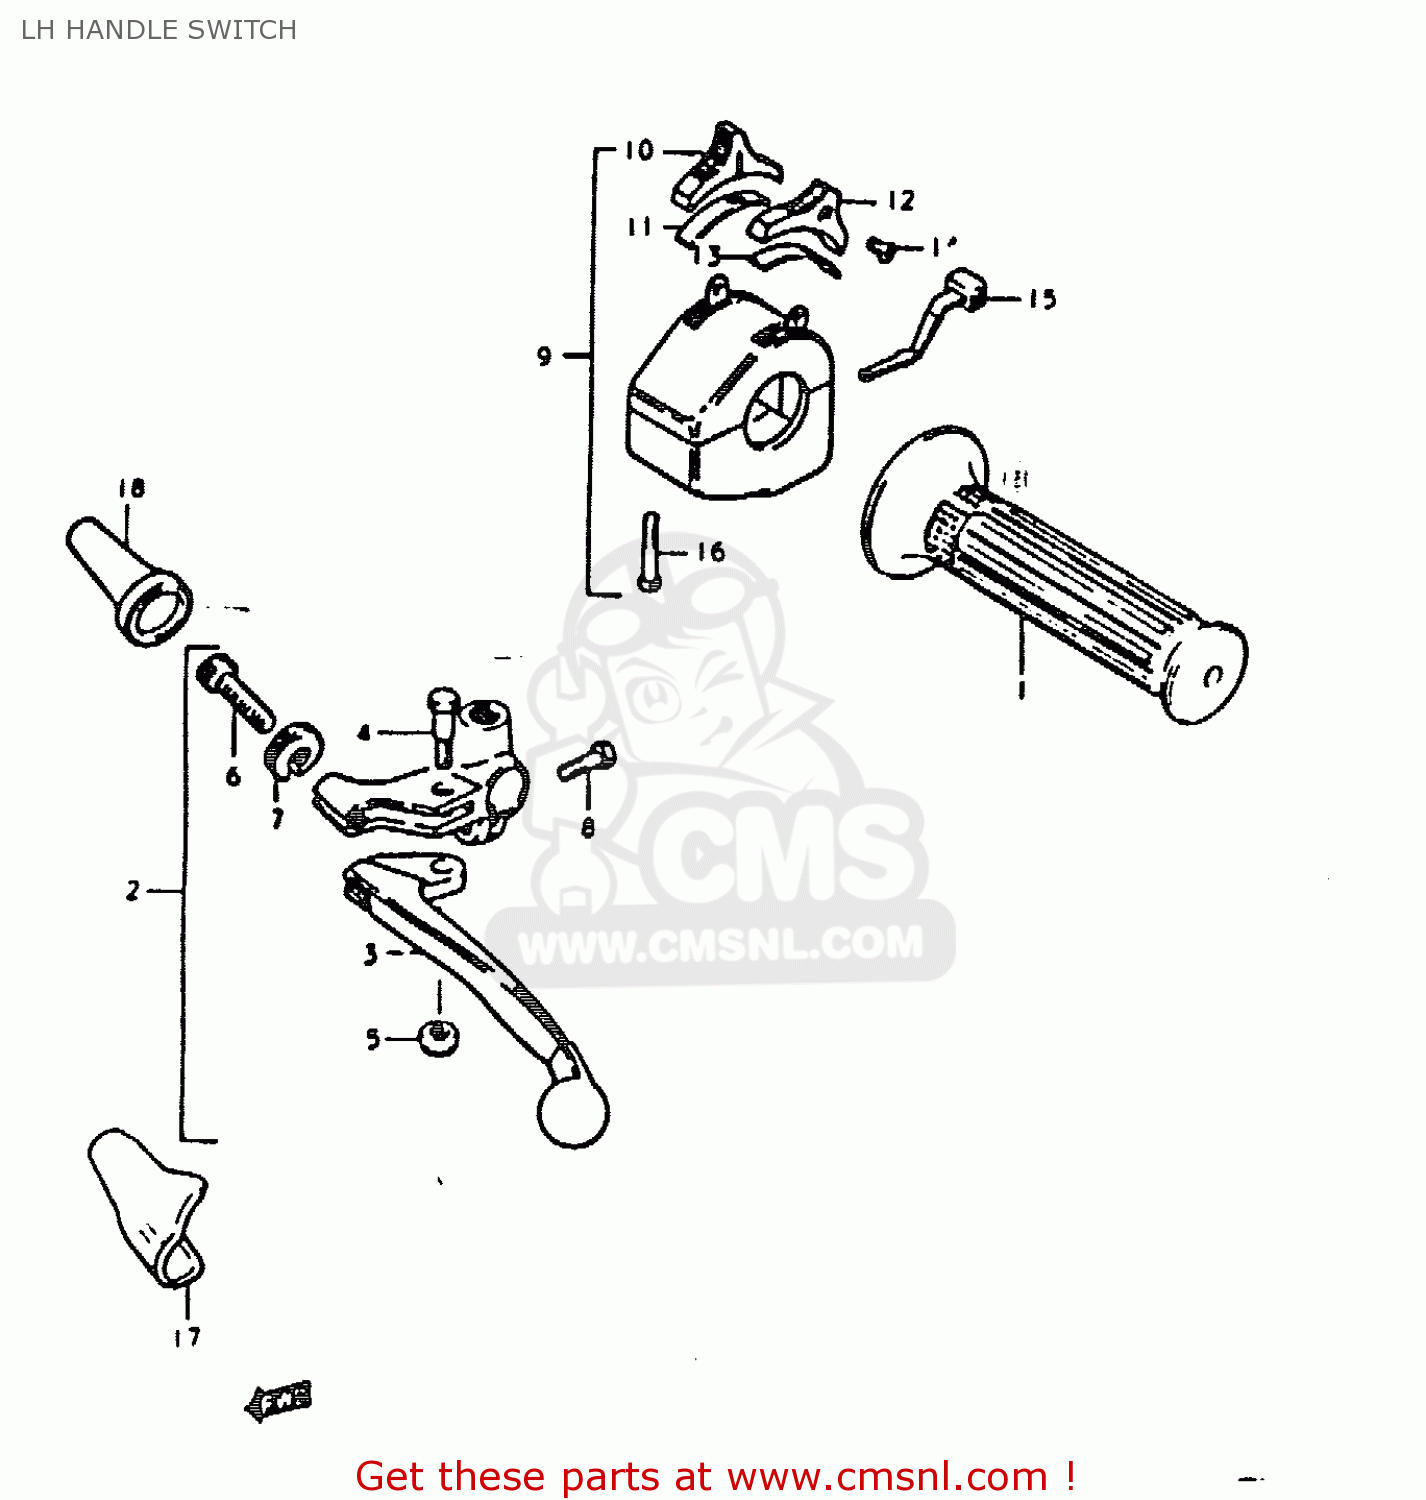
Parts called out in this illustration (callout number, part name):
1	GRIP,L
2	LEVER ASSEMBLY
3	LEVER,CLUTCH
4	BOLT,LEVER PIVOT
5	NUT 6MM
6	ADJUSTER,CABLE
7	NUT,CABLE ADJUSTER
8	BOLT
9	SWITCH ASSEMBLY,HANDLE,LEFT
10	KNOB,HANDLE SWITCH
11	PLATE,SWITCH KNOB
12	KNOB,DIMMER SWITCH
13	SPRING
14	SCREW
16	SCREW
17	COVER,CLUTCH LEVER
18	BOOT,CLUTCH CABLE
